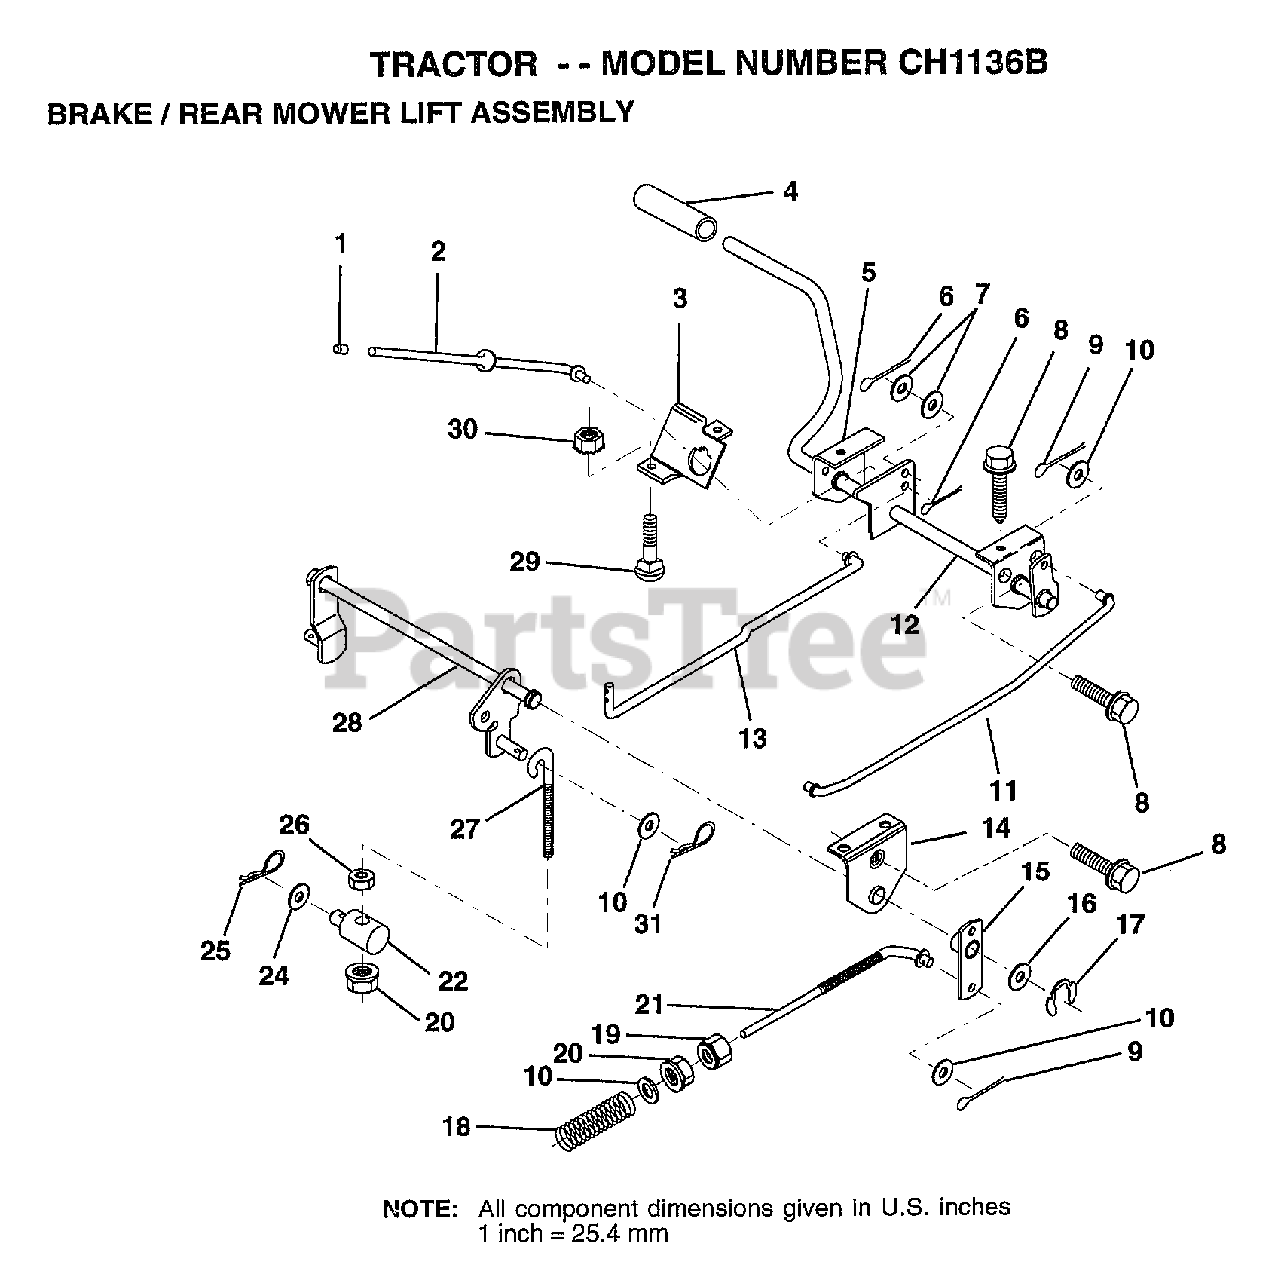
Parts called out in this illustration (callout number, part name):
1	PLUNGER CAP T
2	"ROD,PARK BRAKE"
3	"BRKT,PARK BRAKE"
4	FOOT PEDAL COVER
5	"BRKT,CLU PEDAL LH"
7	WASHER
8	SCREW LT
9	COTTER PIN
10	WASHER
11	"ROD,FRT BRAKE"
12	PEDAL ASM CL/BK36
13	"ROD,CLUTCH"
14	"BRKT,LIFT SHAFT"
15	PVT BRAKE ARM ASM
16	WASHER T
17	KLIP RING
18	SPRING ROD LT
19	NUT
22	TRUNNION.LIFT.
24	WASHER
25	SPRING.RETAINER
26	LOCKNUT
27	"LINK, MOWER REAR"
28	LIFT ASM MOW REAR
31	RETAINER.SPRING
